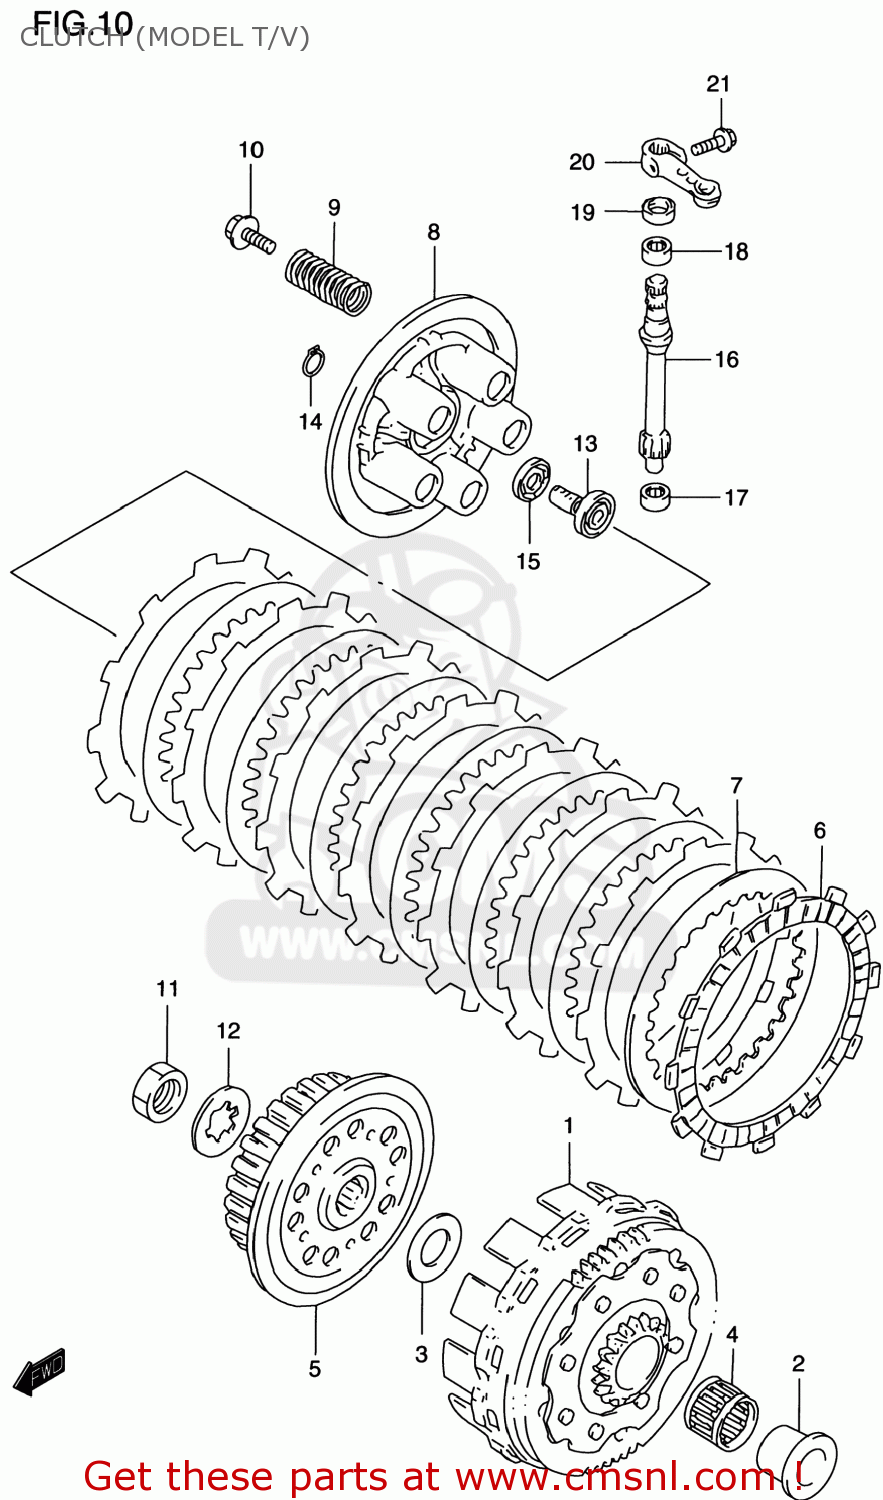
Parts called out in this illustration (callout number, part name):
1	GEAR ASSEMBLY,PRIMARY (NT:6
2	SPACER,PRIMARY DRIVEN GEAR
3	WASHER
4	BEARING(25X30X22)
5	HUB,CLUTCH SLEEVE
6	PLATE,CLUTCH DRIVE(T:2.8) (NAS)
7	PLATE,CLUTCH DRIVEN(T:1.4) (NAS)
8	DISC,CLUTCH PRESSURE
9	SPRING
10	BOLT(5X25)
11	NUT
12	WASHER,LOCK
13	RACK,CLUTCH RELEASE
14	CIRCLIP,10MM
15	BEARING(10X22X2.8)
16	PINION,CLUTCH RELEASE(NT:12)
17	BEARING(9X13X10)
18	BEARING(12X16X10)
19	SEAL,OIL(10X17X5)
20	ARM,CLUTCH RELEASE
21	BOLT
